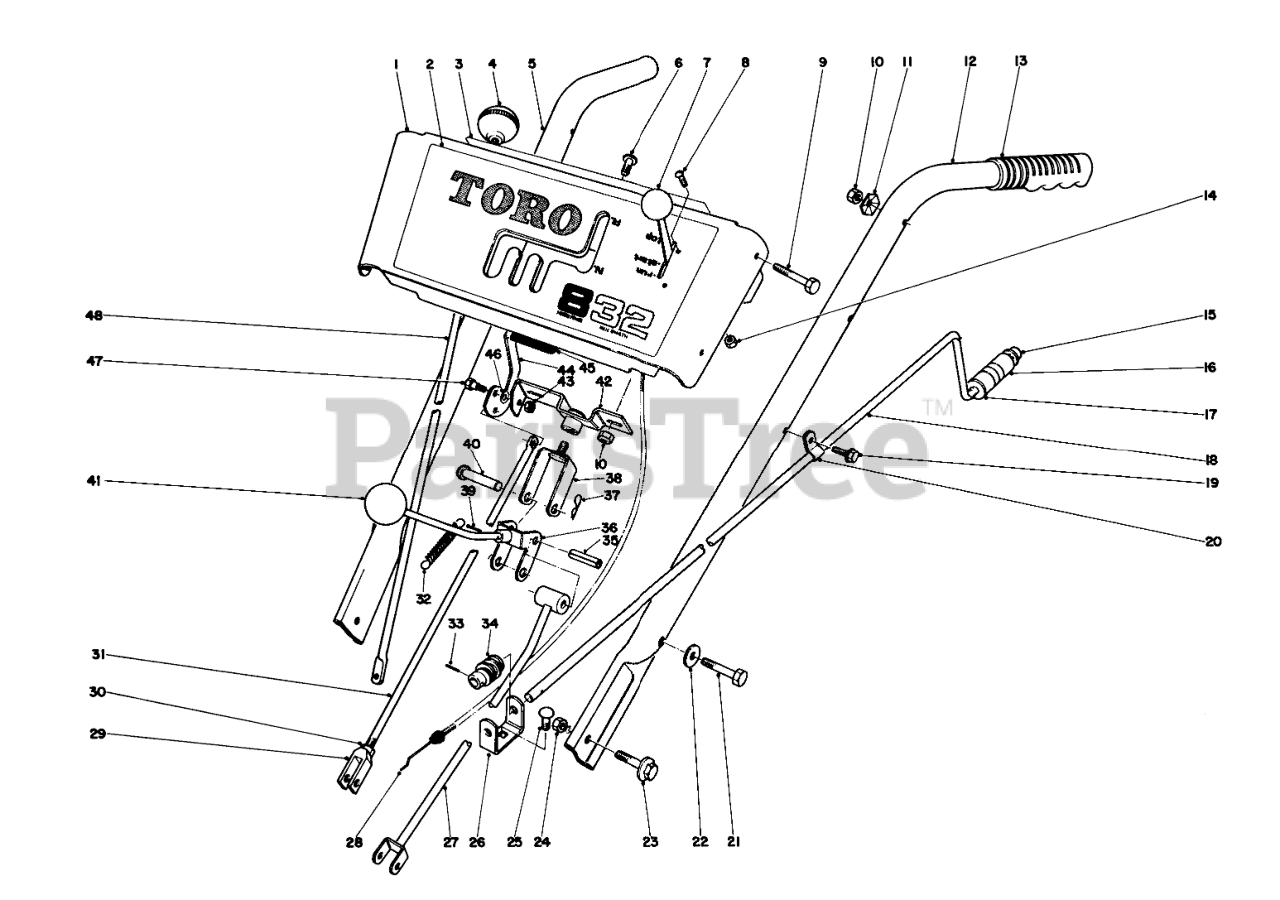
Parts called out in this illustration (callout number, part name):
1	Escutcheon Plate (Incl. Ref. 3)
2	Decal (7 HP)
3	Decal
4	KNOB-LEVER
5	Handle, R.H.
6	Screw, Machine
7	KNOB-CONTROL
8	SCREW-PPH
9	SCREW-HH
10	NUT-LOCK
11	Washer
12	Handle, Left
13	Grip Handle
14	Nut
15	Speed Nut
16	Chute Control Grip
17	WASHER-FLAT
18	ROD CHUTE CONTROL
19	Hex Hd. Screw
20	R-CLAMP
21	SCREW-HH
22	WASHER-FLAT
23	SCREW-HHF
24	NUT-HEX
25	SCREW-CARR
26	WORM BRACKET
27	Trunnion
28	Throttle Contrl
29	Yoke
30	NUT-HJ
31	Drag Link
32	CONT ROD SPRING 0
33	PIN-SPRING
34	GEAR-WORM, CHUTE
35	PIN-ROLL
36	Rod Shift
37	PIN-HAIR
38	Pivot Bracket
39	PIN-COTTER
40	PIN-CLEVIS
42	SWIVEL BLOCK WA
43	NUT-LOCK
44	Handle, Auger
45	AUGER CLUTCH HND GRIP
46	WASHER-PLAIN
47	SCREW-SHOULDER
48	Rod Wheel Clutch
